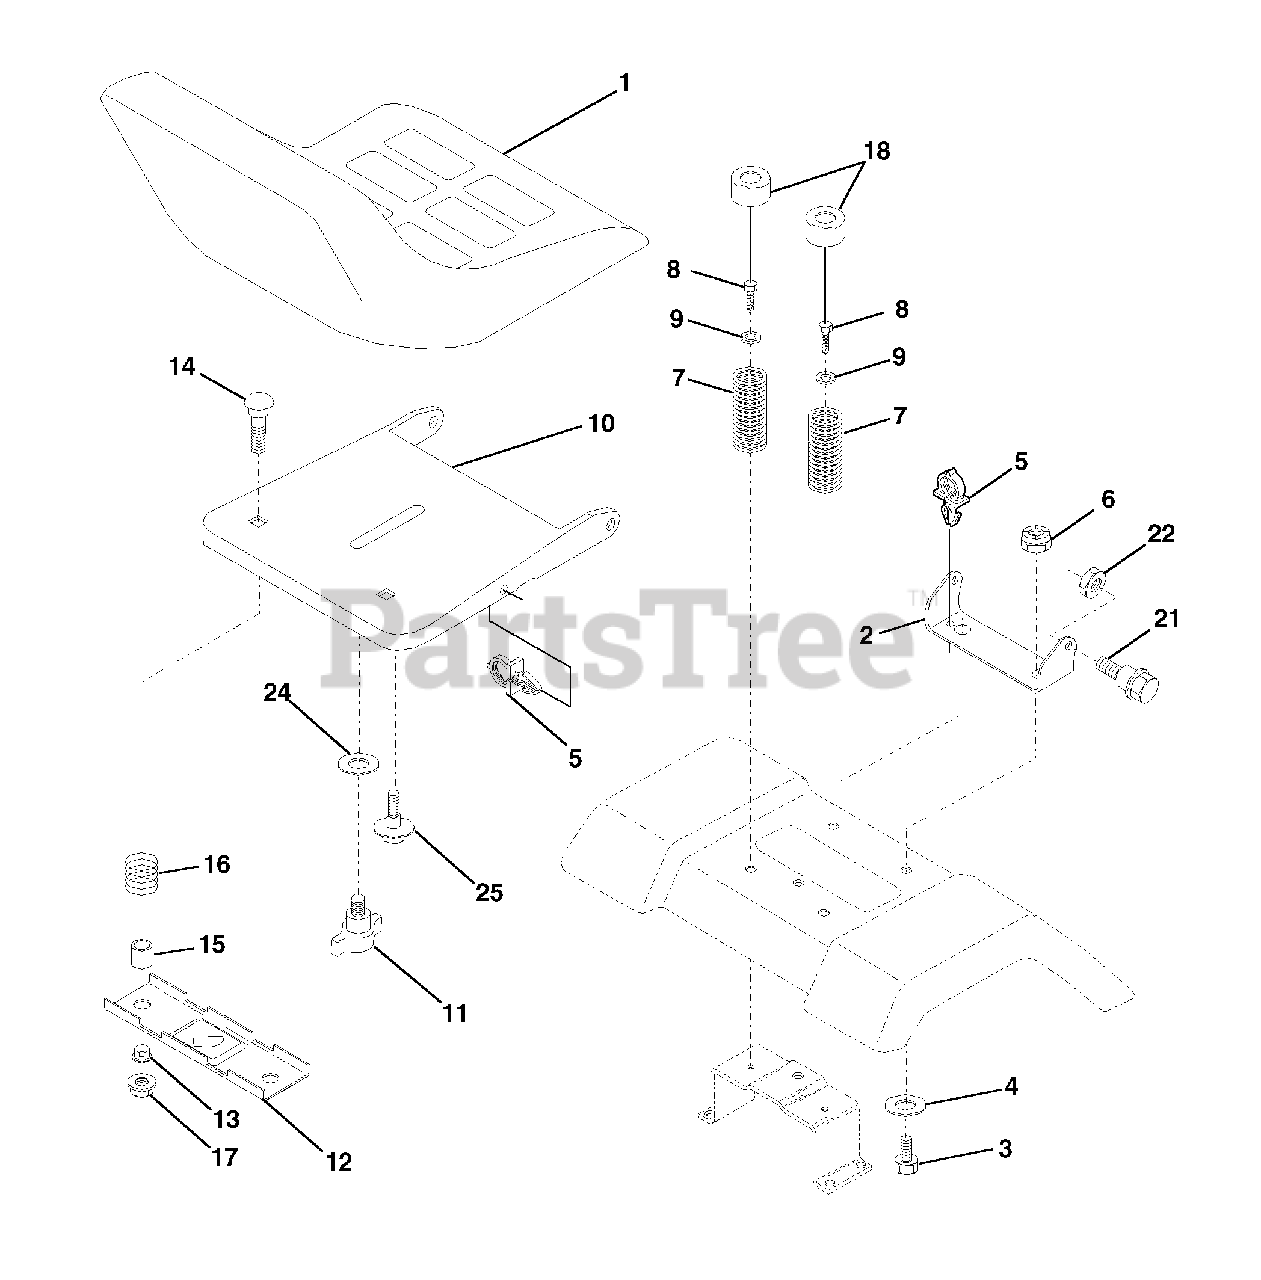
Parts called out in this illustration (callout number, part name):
1	Seat
2	Bracket Pivot Seat 8 720
3	Bolt Fin Hex 3/8-16unc X 1
4	Washer 13/32 X 1 X 10 Ga
5	Clip Push-In
6	Nut Hex w/Ins. 3/8-16 Unc
7	Spring Seat Cprsn 2 250 Blk Zi
8	Screw Thdrol 3/8-16 X 1 Ty-tt
9	Washer 13/32 X 1 X 14 Ga.
10	Pan Seat
11	Knob Seat 1/2-13 UNC Blk
12	Bracket Mounting Switch
13	Bushing Snap Blk Nyl 50 Id
14	Bolt Rdhd Sqnk 1/4-20x1-1/2
15	Spacer Split 28x 96 Yel Zinc
16	Spring Cprsn 1 27 Blk Pnt
17	Nut Lock 1/4 Lge Flg Gr 5 Zinc
18	Cap Spring Seat
21	Bolt Shoulder 5/16-18 Unc
22	Nut Hex Lock W/Ins 5/16-18
24	Washer 17/32 X 1-3/16 X 12 Ga.
25	Bolt Shoulder 5/16-18 X 62
